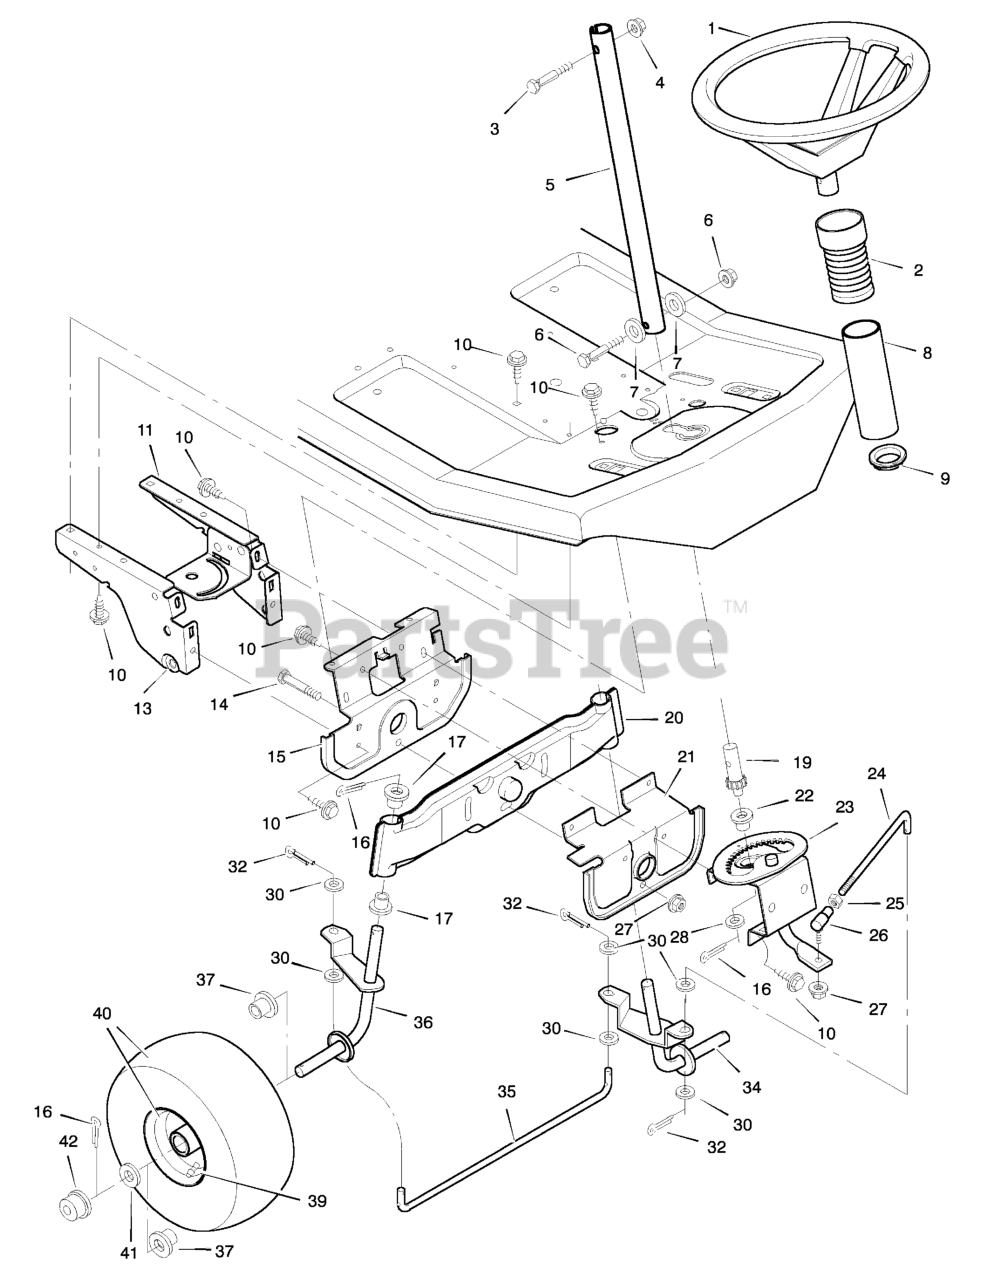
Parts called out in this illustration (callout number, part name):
1	Steering Wheel
2	Bellows
3	Bolt, Hex
4	Locknut, Flange
5	Post, Steering
6	Nut, Hex
7	Washer
8	Cover, Steering Post
9	Bearing
11	Plate, Left Suspension
13	Plate, Right Suspension
14	Bolt, Hex
15	Support, Front Axle
16	Pin, Cotter
17	Bearing, Spindle
19	Gear, Pinion
20	Axle Assembly, Front
21	Hanger Assembly, Front Axle
22	Bearing
23	Sector Assembly
24	Rod, Drag Link
25	Nut, Hex
26	Ball Joint, Steering
27	Locknut, Flange
32	Pin, Cotter
34	Spindle Assembly, Left
35	Rod, Tie
36	Spindle Assembly, Right
37	Bearing, Wheel
39	Valve Stem
40	Wheel & Tire Assembly
42	Cap, Hub
